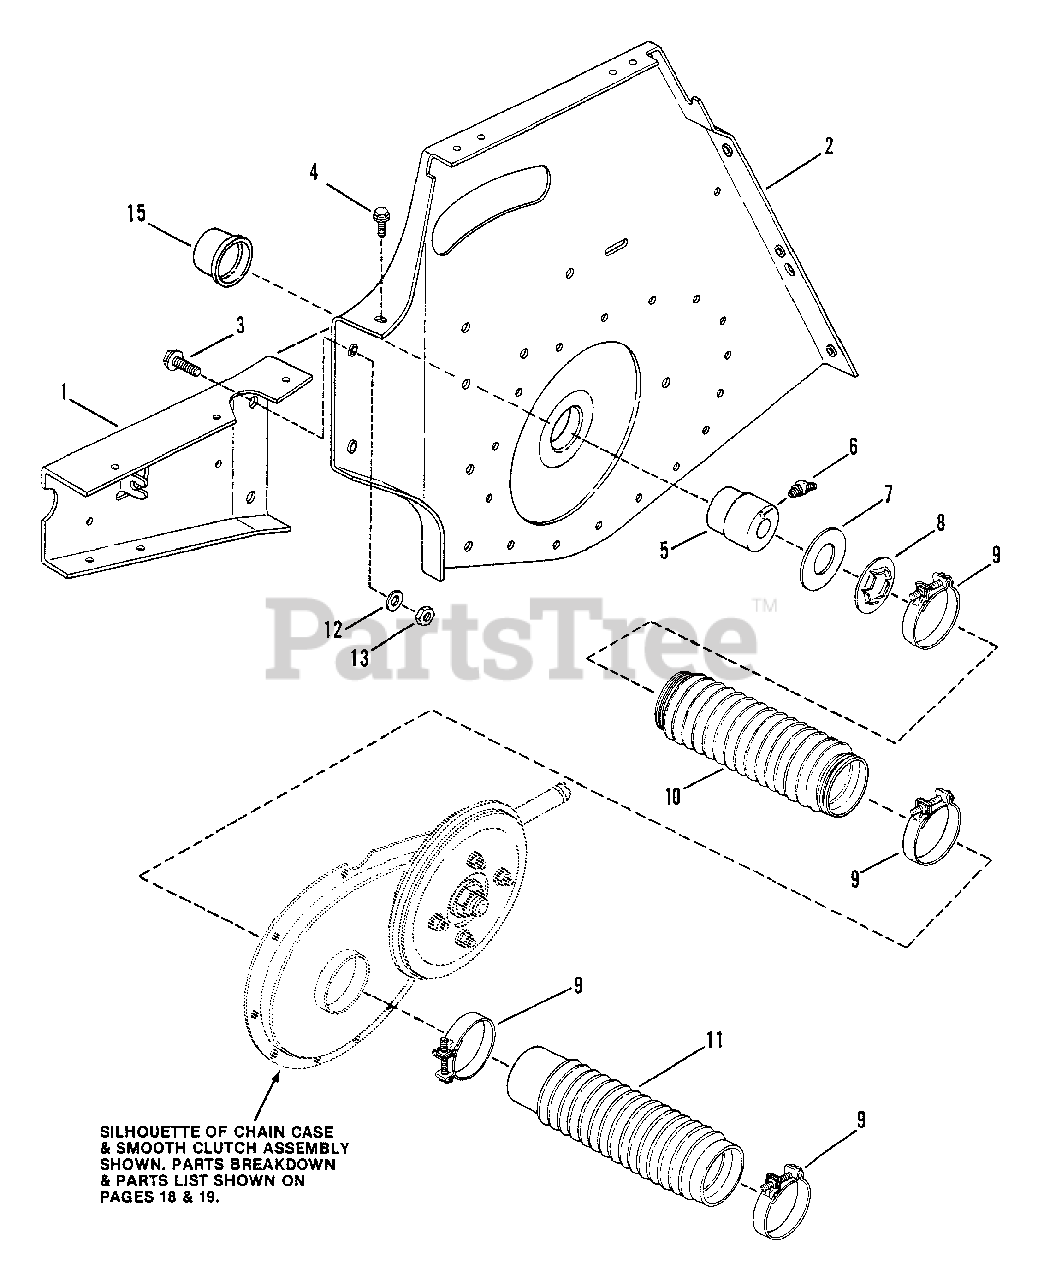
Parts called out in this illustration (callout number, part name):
1	EXTENSION, Transmission support (Right Hand)
2	SUPPORT, Transmission (Right Hand)
3	BOLT, 3/8-16 x 1" Hex Flange Lock
4	SCREW, 5/16-18 x 5/8" self-Tapping
5	ASSEMBLY, Axle Bearing
6	FITTING, Lube
7	WASHER, Thrust
8	WASHER, Thrust (Hex Drive Tube)
9	CLAMP, Boot
10	BOOT, Oil Seal
11	BOOT, Oil Seal
12	WASHER, 318 Flat
13	NUT, 3/8-16 Hex Center Lock
15	CAP, Seal L.H. 3/4"
